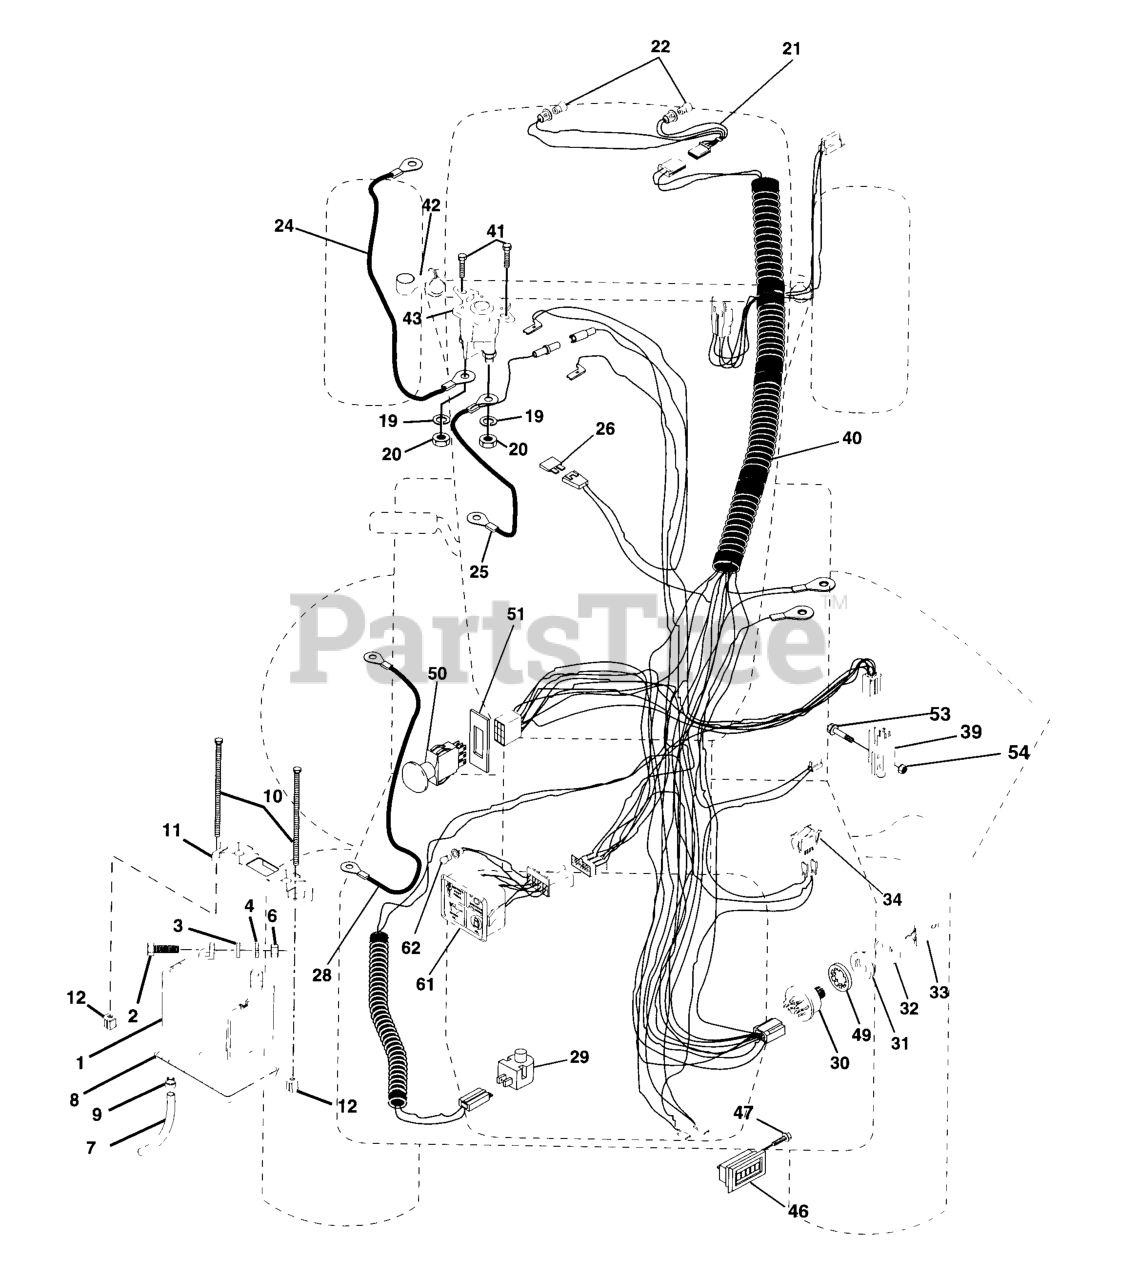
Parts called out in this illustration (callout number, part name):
1	BATTERY 12V .35 AMP
2	BOLT.HEX.1/4.X.3/4.DICHROMATE
3	LOCKWASHER
4	WASHER
6	NUT
7	PLASTIC TUBE
8	BATTERY TRAY T
9	HOSE CLAMP T
10	BOLT 1/4-20 X 7.5
11	HOLDDOWN, BATTERY, DASH MOUNT
12	NUT, PUSH NYLON 1/4" BATTERY
19	LOCKWASHER
20	NUT
21	HARNESS LIGHT SOCKET
24	CABLE, STARTER
25	CABLE, BATTERY
28	CABLE, GROUND
29	RP.SWITCH.PLUNGER.NC.GRAY
30	IGNITION SWITCH
31	NUT, IGNITION
32	COVER SWITCH KEY
33	KEY MLD GEN DELTA
39	SWITCH INTERLOCKT
40	HARNESS, IGNITION
41	SCREW
42	TERMINAL COVER
43	SOLINOID
46	HOUR METER T
47	Screw #10-24 x 1/2
49	Washer, Lock internal Tooth 5/8
50	SWITCH-PTO
51	FRAME RETAINING RING
53	SCREW **
54	Nut Keps #10-32
61	LIGHT PACKAGE
62	BULB LIGHT T
